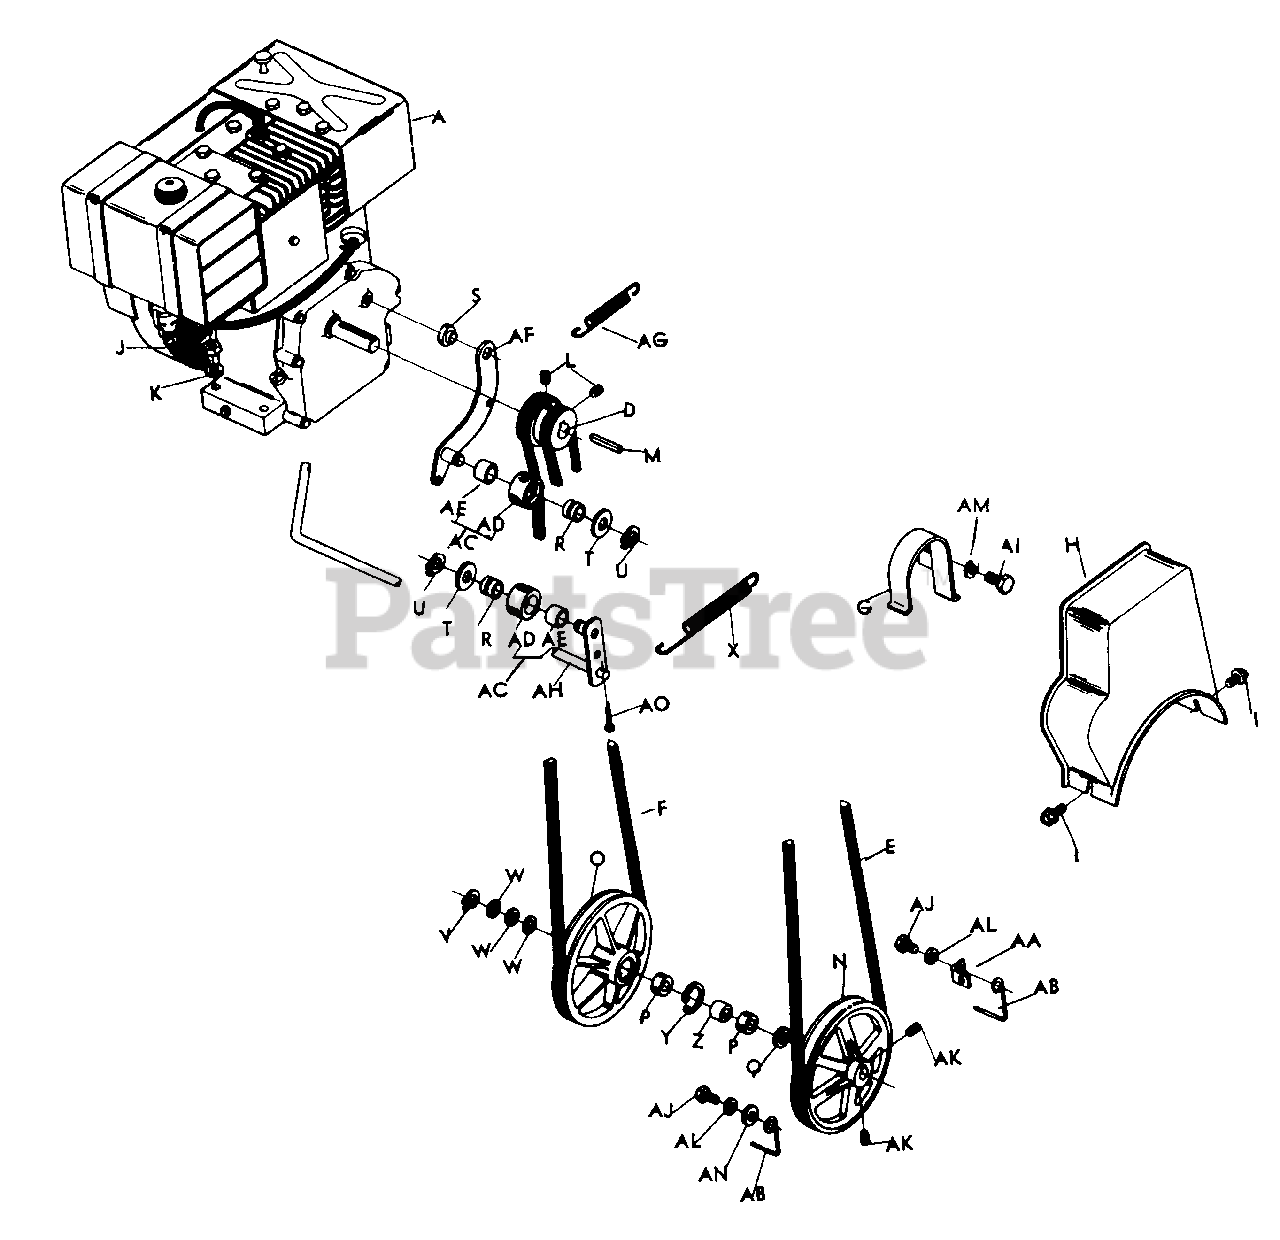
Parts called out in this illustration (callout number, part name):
H	Belt Guard Assembly
I	Lock Screw 1/4-20 x 1/2-Pl.
J	5/16-18 Hex Nut-Pl.
K	5/16 Lockwasher-Pl.
N	Pulley-Impeller Drive
O	Pulley-Traction Drive
P	Bearing
Q	Spacer
R	Bushing
S	Pivot Bushing
T	Washer
U	Retaining Ring
V	Retaining Ring
W	Washer
X	Spring
Y	Retaining Ring
Z	Spacer
AA	Spring Bracket
AB	Belt Finger
AC	Idler & Bearing Assembly
AD	Idler
AE	Bearing
AF	Idler Arm Assembly
AG	Spring
AH	Idler Arm Assembly
AI	1/2-20 x 1 1/4 Hex Hd. Capscrew-Pl.
AJ	1/4-20 x 3/4 Hex Hd. Capscrew-Pl.
AK	3/8-16 x 3/4 Sq. Hd. Setscrew-H.T. & Pl.
AL	1/4 Lockwasher-Pl.
AM	1/2 Lockwasher-Pl.
AN	1/4 Flat Washer-Pl.
AO	1/8 x 3/4 Cotter Pin-Pl.
